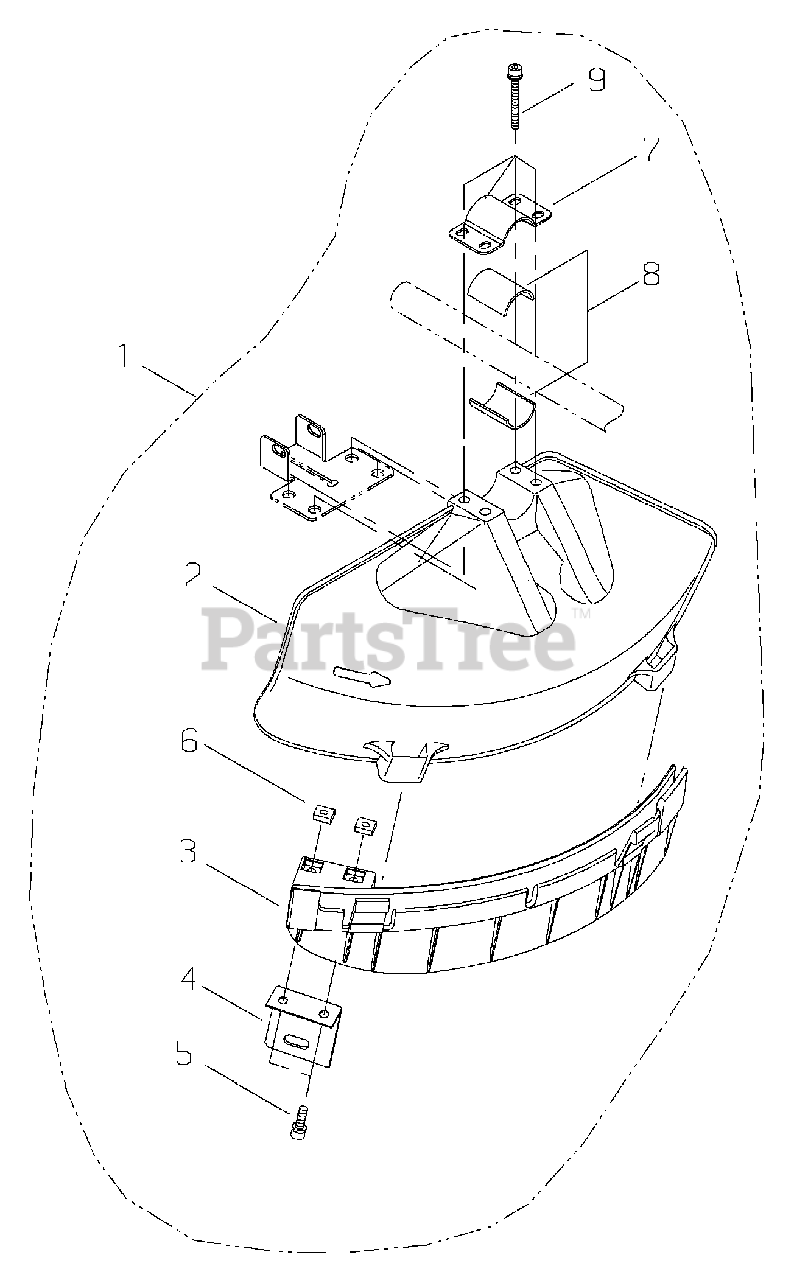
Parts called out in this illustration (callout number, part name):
1	DEBRIS SHIELD KIT
2	SHIELD, DEBRIS
3	SUBGUARD
4	CUTTER
5	BOLT M5×16
6	NUT M5
7	CLAMP, UPPER
8	SPACER
9	BOLT M5×45
